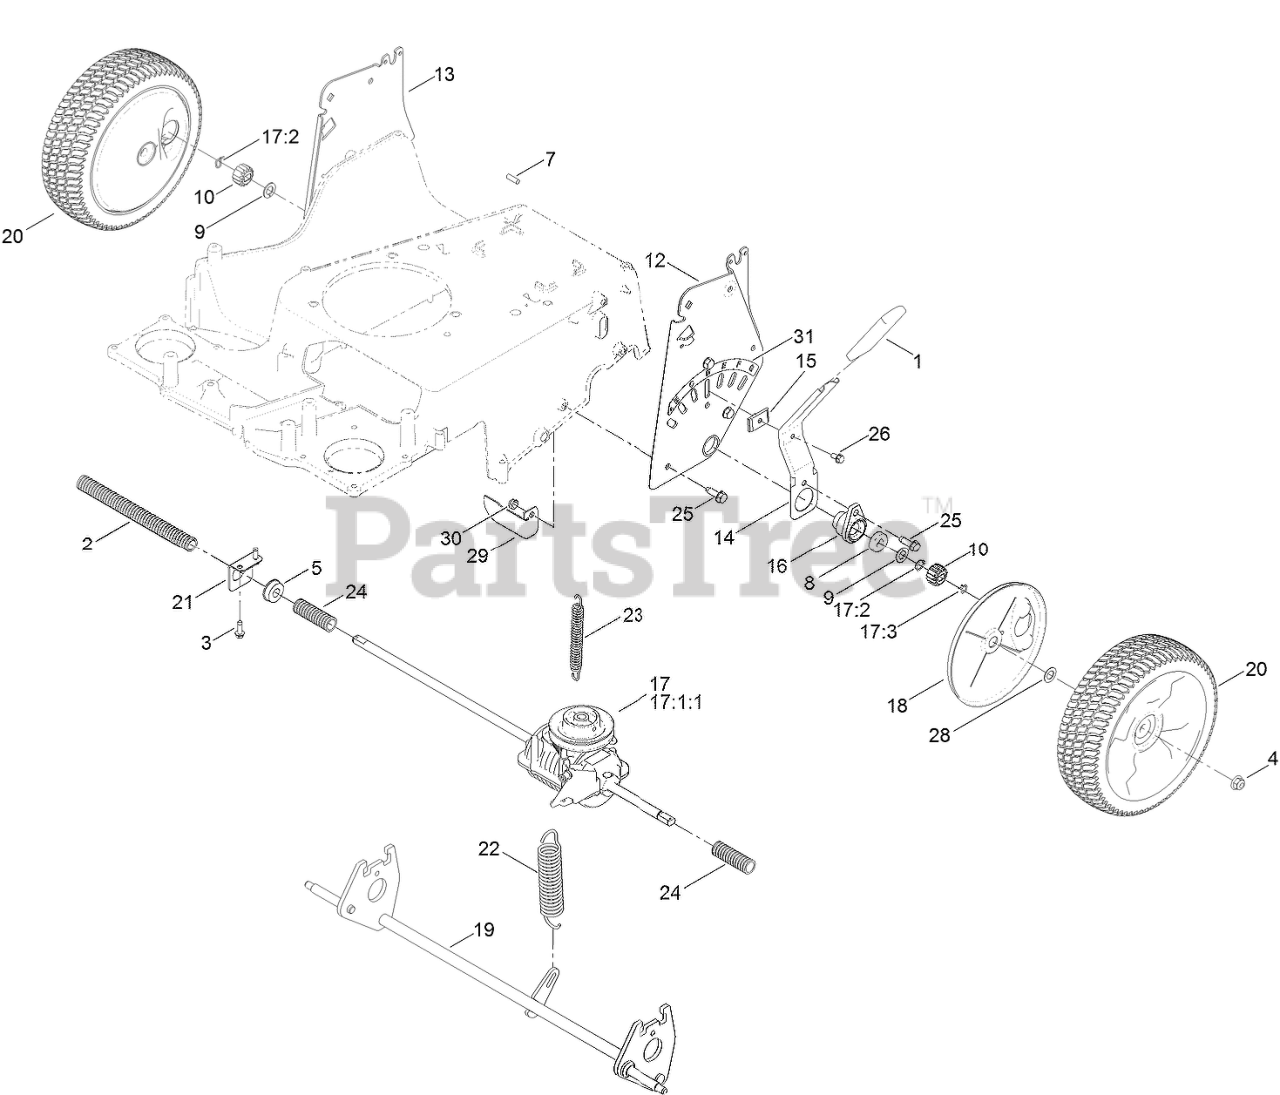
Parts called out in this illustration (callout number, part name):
1	GRIP-LEVER, LIFT
2	CONDUIT-CONVOLUTED
3	SCREW-HWHTF
4	NUT-HF, NI
5	BEARING-BALL
7	PIN-STOP
8	BEARING-BALL
9	WASHER-THRUST
10	GEAR-PINION, 15T
12	PLATE-HOC, LH
13	PLATE-HOC, RH
14	ARM-SPRING, REAR
15	KEY-SPRINGARM
16	RETAINER-BEARING
17	TRANSMISSION KIT
17:1:1	TRANSMISSION PULLEY KIT
17:2	PIN-SNAP
17:3	RING-RETAINING
18	COVER-GEAR
19	AXLE-REAR
20	10 INCH WHEEL GEAR ASM
21	MOUNT-BEARING
22	SPRING-EXTENSION
23	SPRING-EXTENSION
24	CONDUIT-CONVOLUTED
25	SCREW-HWHTF
26	SCREW-HWH
28	WASHER-PLAIN
29	BRACKET-STOP
30	NUT-LOCK, NI
31	DECAL-HOC, REAR
